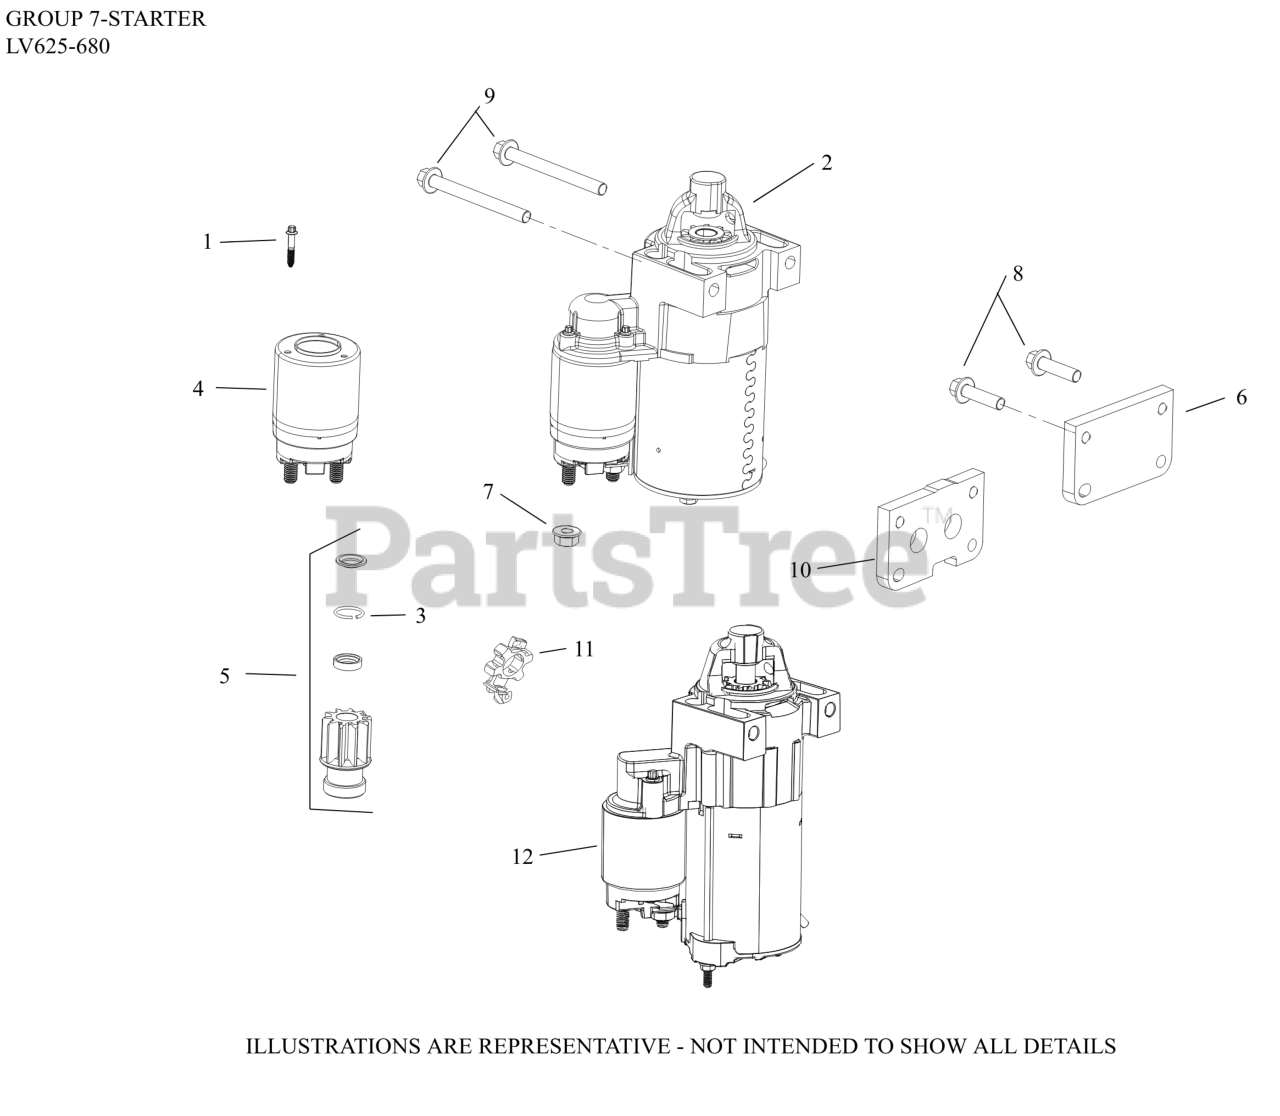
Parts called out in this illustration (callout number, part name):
2	STARTER, SOLENOID SHIFT-(#2509824S)
6	PLATE, STARTER
7	NUT, FLG M8X1.25
8	SCREW, FLG M8X1.25X30
9	SCREW, FLG M8X1.25X80
